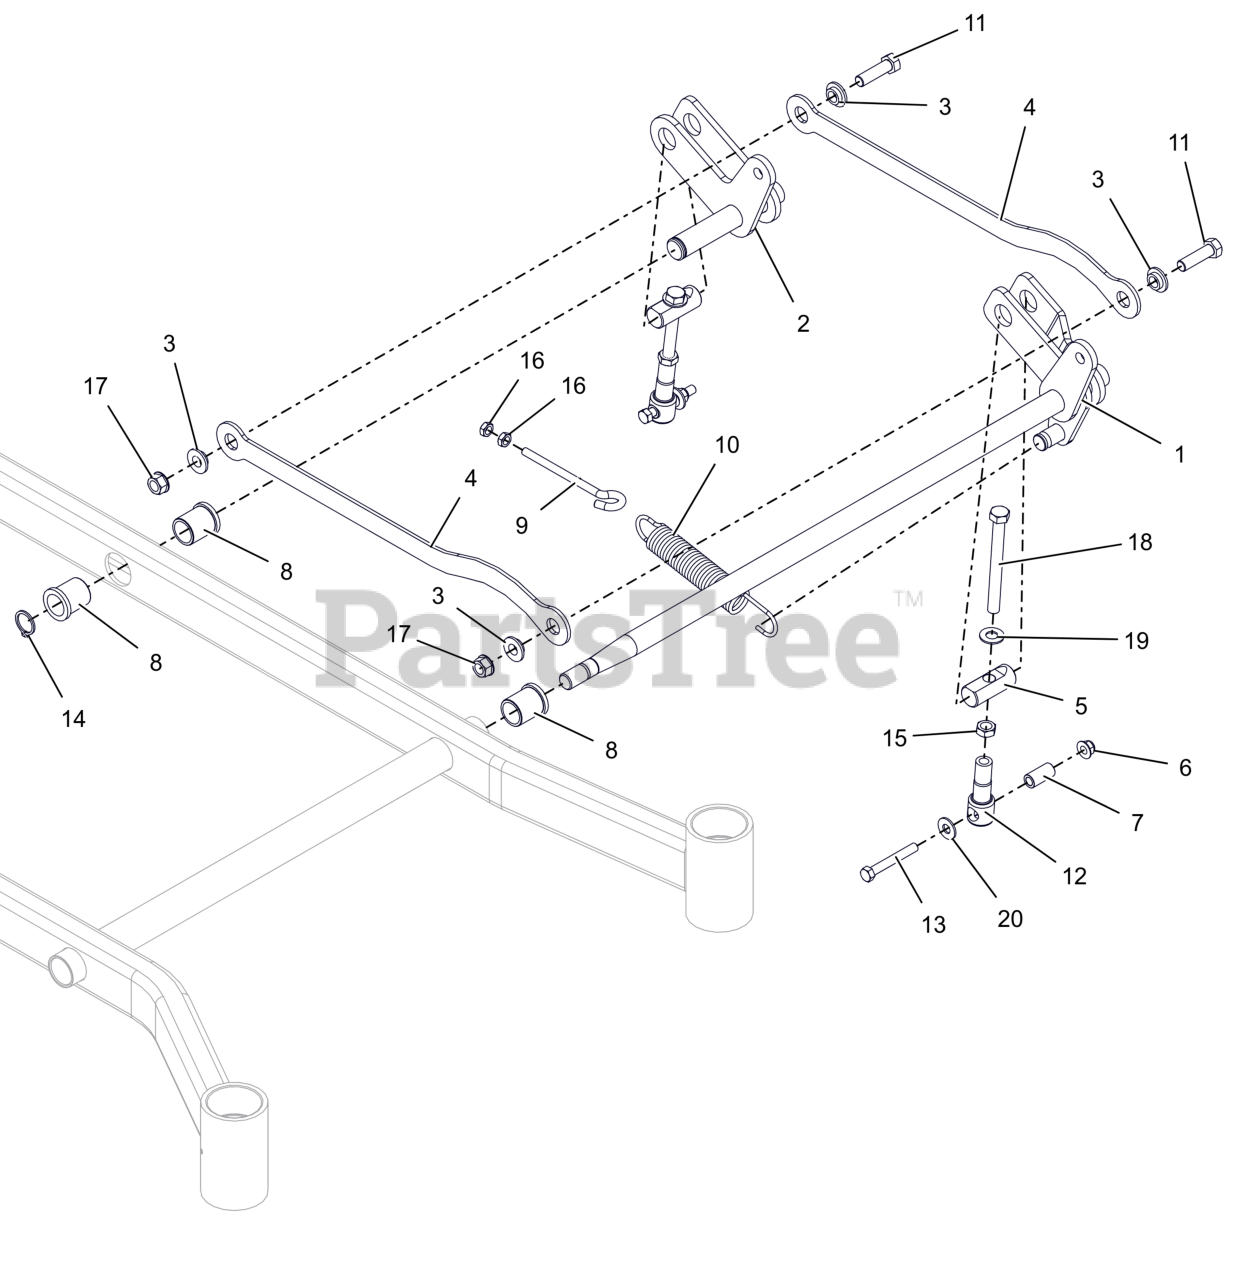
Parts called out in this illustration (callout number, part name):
1	FRT LH DECK LIFT ARM WMT- LF
2	WLDMT, REAR LH DECK ARM
3	BSHG-FLG .515X.750X.310X1.120
4	LINK, LIFT
5	PIN, DECK LIFT
6	NUT,NYL-FLG .38-16 GF ZCC
7	SPACER, DECK LEVELING
8	BSHG-FLG 1.00X1.25X1.50X1.50
9	BOLT,.38-16 X 4.25-.62 DIA EYE
10	SG-TENS .162X1.25X8.25 WLD 25
11	BLT, HEX .50-13X1.75 G5 ZCC
12	LINK, DECK LIFT FORMED
13	BLT, HEX .38-16X2.75 G8 ZCC
14	RG-RTNG-EXT 1.00X.078
15	NUT-JAM .500-13 G2 ZCC
16	NUT-JAM .375-16 G2 ZCC
17	NUT-LK-CTR-FLG .500-13 GG ZCC
18	BLT, HEX 0.5-13X5S GR5 ZCC
19	WSHR, FLT .557X1.040X.102 ZCC
20	WSHR,FLT .438X1.00X.083 ZCC
